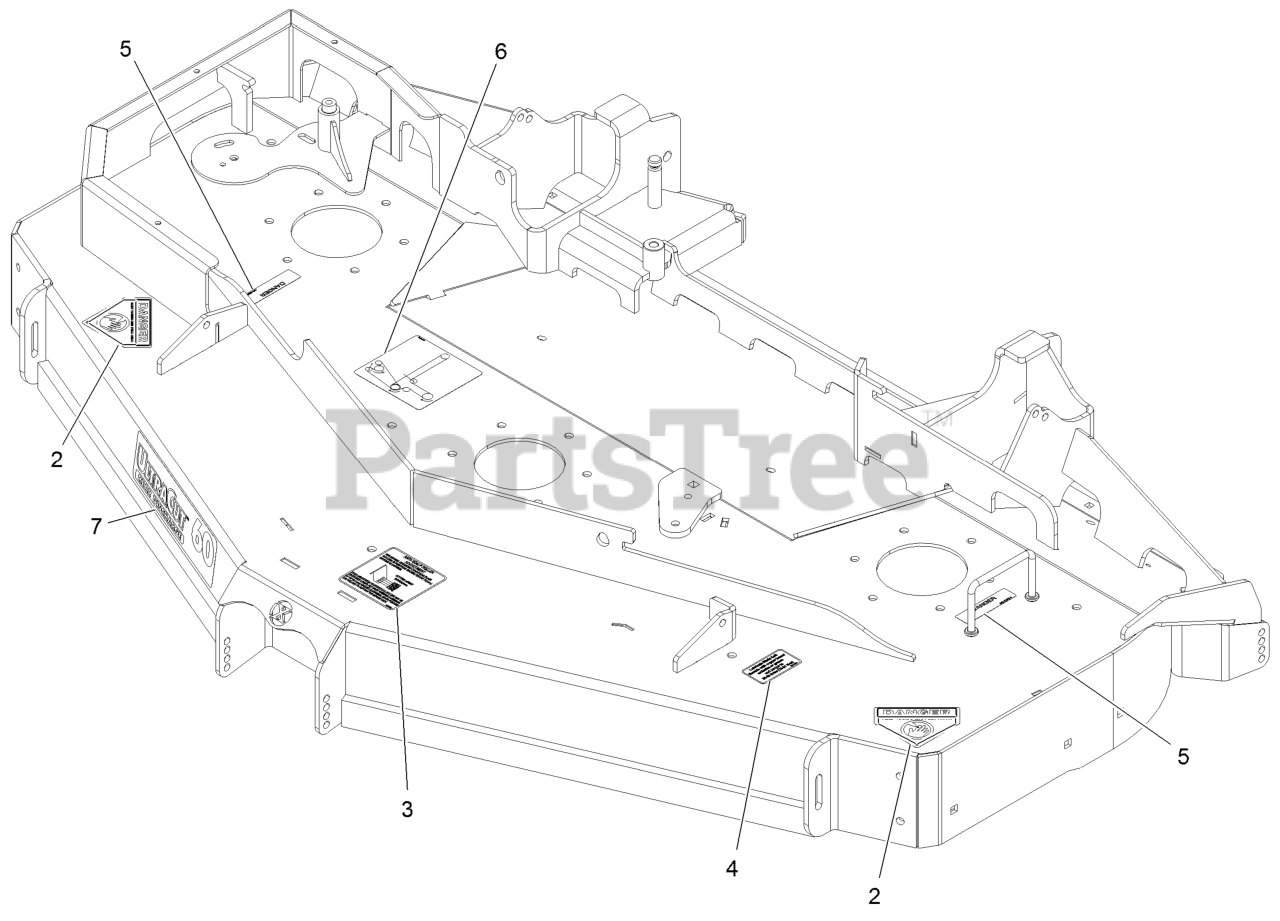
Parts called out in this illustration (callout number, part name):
2	DECAL-DANGER
3	DECAL,ANTISCALP
4	DECAL,BOLT TORQUE
5	DECAL-COVER, MISSING
6	DECAL-ROUTING, BELT
7	DECAL,REAR DISCHARGE 60
